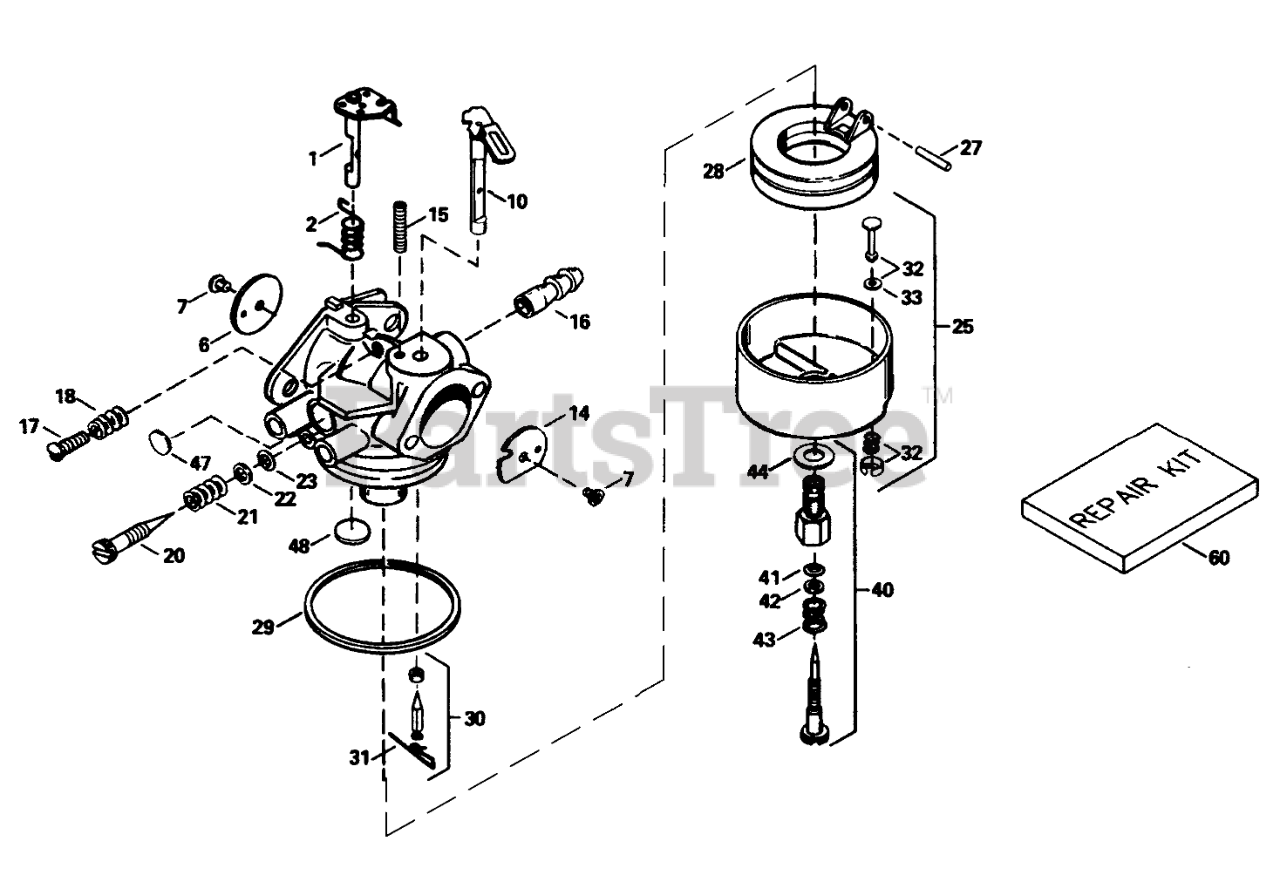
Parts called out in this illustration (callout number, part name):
1	Throttle Shaft and Lever ASM
2	Spring-Return, Throttle
6	Shutter-Throttle
7	Screw-Shutter
10	Choke Shaft and Lever ASM
14	Shutter-Choke
15	Spring-Positioning, Choke
16	Fitting-Fuel
17	Screw-Throttle Crack Screw / Idle Speed
18	Spring-Tension
20	Screw-Idle Mix
21	Spring-Tension
23	"O"Ring
25	Float Bowl (Incl. Ref. #32 & 33)
27	Shaft-Float
28	Float
29	O Ring-Bowl, Float
30	Inlet Needle, Seat & Spring Clip (Incl Ref. #31)
31	Clip-Spring
32	Bowl Drain Assy. (Incl Ref. #33)
33	Gasket-Plunger, Drain
40	Mian Adj. Screw Asm.
41	"O"Ring
44	Washer-Bowl Nut
47	Plug-Welch, Idle Mixture Well
48	Plug-Welch, Atmospheric Vent
60	Repair Kit (Incl. Ref. #23, 27, 29-30, 41, 44, & 47-48)
